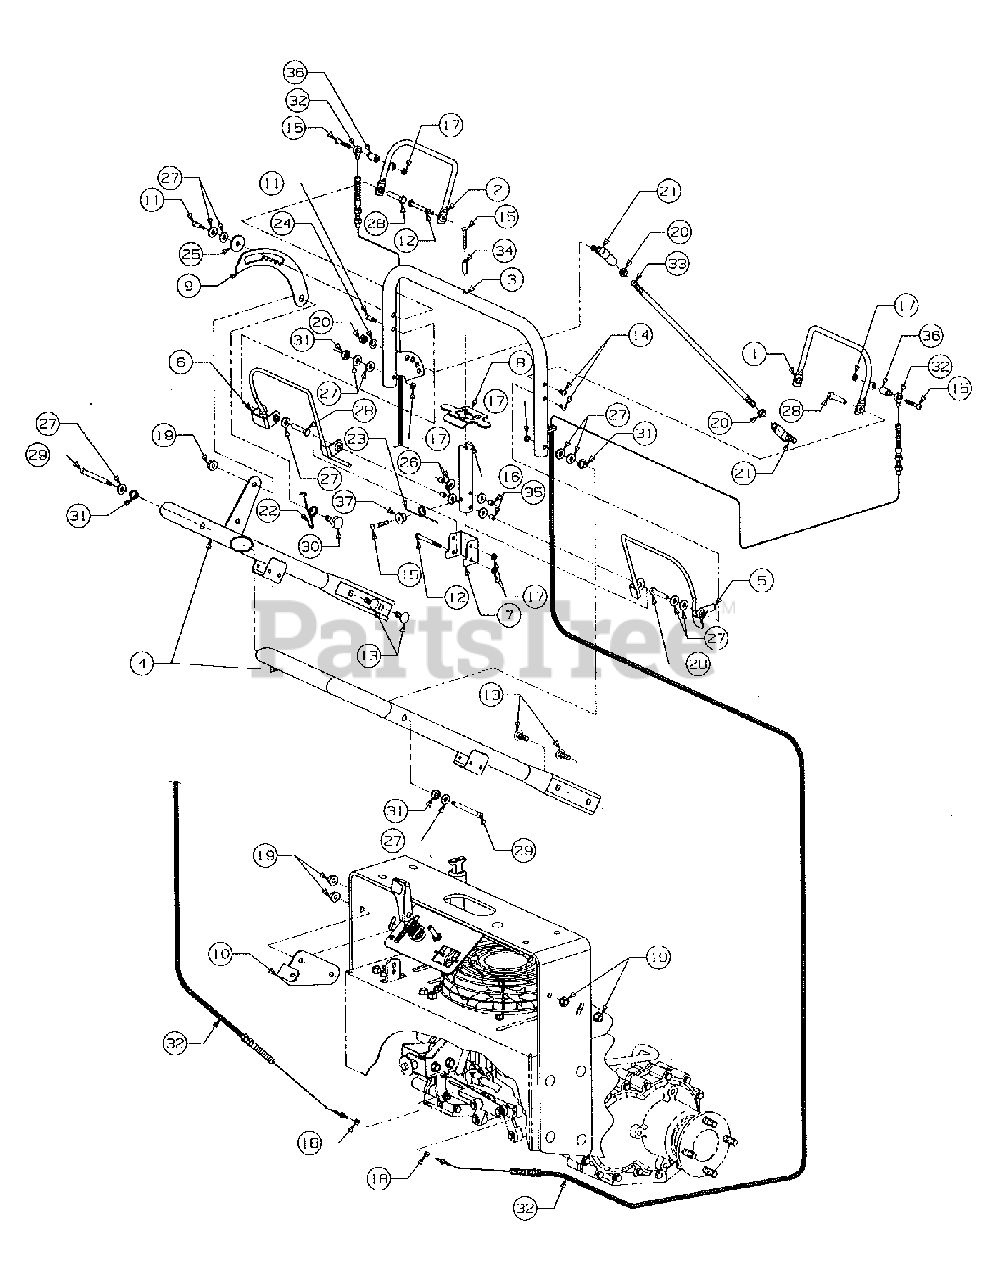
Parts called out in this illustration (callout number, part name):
1	Lever w/Bushing, RH Brake
2	Lever w/Bushing, LH Brake
3	Bar w/Graphics, Traction Control
3	Graphic, F-N-R
3	Graphic, Traction Control
4	Bar, Lower Handle
5	Lever w/Bushings, Operator Present
6	Lever w/Bushings & Graphic, Speed set
6	Graphic, Speed Set
7	Stop, Handle
8	Latch w/Graphic, Park Brake
8	Graphic, Park Brake
9	Plate, Speed Set
10	Bracket, Trans Release, cable Mtg
11	Screw, Socket Hd Shoulder
12	Screw, Hex Cap, 1/4-20 x 2.50 Gr 5
13	Bolt, Carriage, 3/8-16 x 1.0 Gr 5
14	Screw, Button Hd, 1/4-20 x .50
15	Screw, Button Hd, 1/4-20 x 1.50
16	Post, Park Brake
17	Nut, Hex Toplock, 1/4-20
18	Nut, Hex #20-32
19	Nut, Hex Flanged Lock, 3/8-16
20	Nut, Hex Jam, 3/8-24 Gr 5
21	Ball Joint, 3/8-24
22	Spring, Torsion
23	Spring, Torsion
24	Washer, Lock 3/8
25	Washer, Flat .32 x 1.25 x .06 Thk
26	Washer, Flat .281 x .75 x .105 Thk
27	Washer, Flat .312 x .75 x .119 Thk
28	Bolt, Shoulder
29	Bolt, Socket Hd Shoulder
30	Bolt, Stepped Shoulder
31	Bushing, Nylon
32	Cable, Brake Clutch
33	Rod, F/R Control
34	Spacer, 5/16 OD x 1/4 x ID x .94
35	Spacer, 5/16 OD x 1/4 x .375
36	Spacer, Cable
37	Spacer, Spring Mtg
